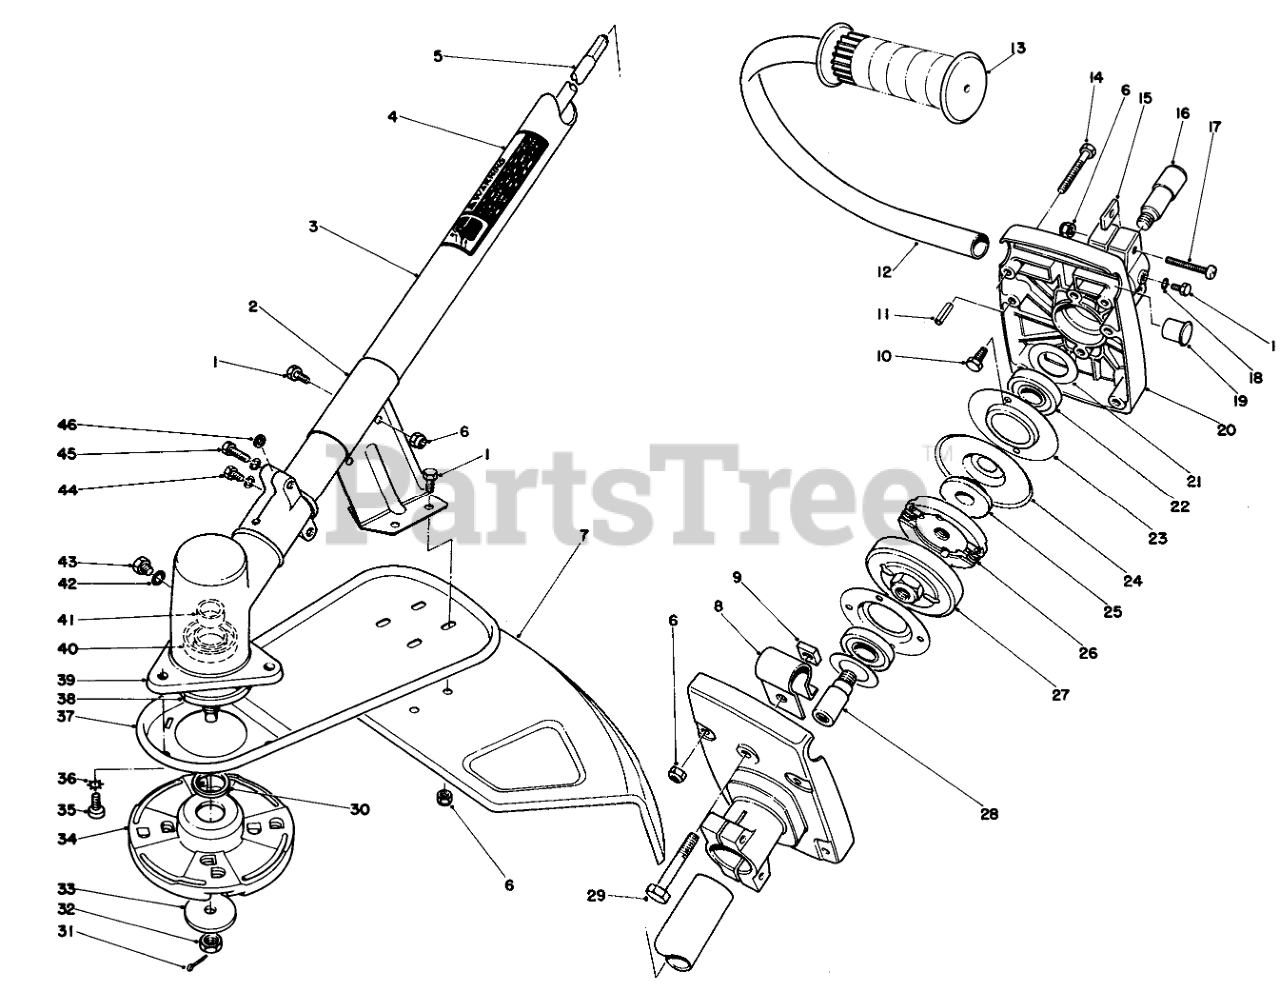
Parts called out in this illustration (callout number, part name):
1	SCREW-SHH
2	SHIELD BRKT
3	Lower Tube Assembly (Incl. Ref. #4)
4	Decal
5	Drive Shaft
6	NUT-LOCK, NI
7	GRASS SHIELD R
8	Clamp-Handle
9	Nut-Square
10	SCREW-TAPTITE
11	PIN-SPRING
12	J-Handle
13	LH GRIP
14	Screw-Machine Hex. Hd.
15	Washer-Housing
16	Shaft-Clutch, Input
17	Screw-Machine Cross Recess Pan Hd.
18	WASHER-LOCK/SP
19	Plug Cap
20	Housing-Clutch
21	FLAT WASHER
22	Bearing
23	Retainer-Bearing
24	CLUTCH SHIELD-WILLMAR
25	Spacer-Clutch
26	Clutch Assembly
27	Drum Assembly
28	Shaft-Clutch, Output
29	SCREW-HH
30	SPACER
31	1/16 X 1 LG COTTER PIN
32	Nut-Special, L.H. Metric
33	WASHER
34	Cutter Head (Incl. Ref. #30)
35	SCREW
36	WASHER-LOCK, EXT
37	SHIELD SUPPORT R
38	DUST CAP F/W
39	Gear Case Assembly (Incl. Ref. #38, 40-46)
40	OIL SEAL
41	SPLINED SLEEVE
42	GASKET
43	HHMS SCREW
44	HHMS SCREW
45	HHMS SCREW
46	WASHER
